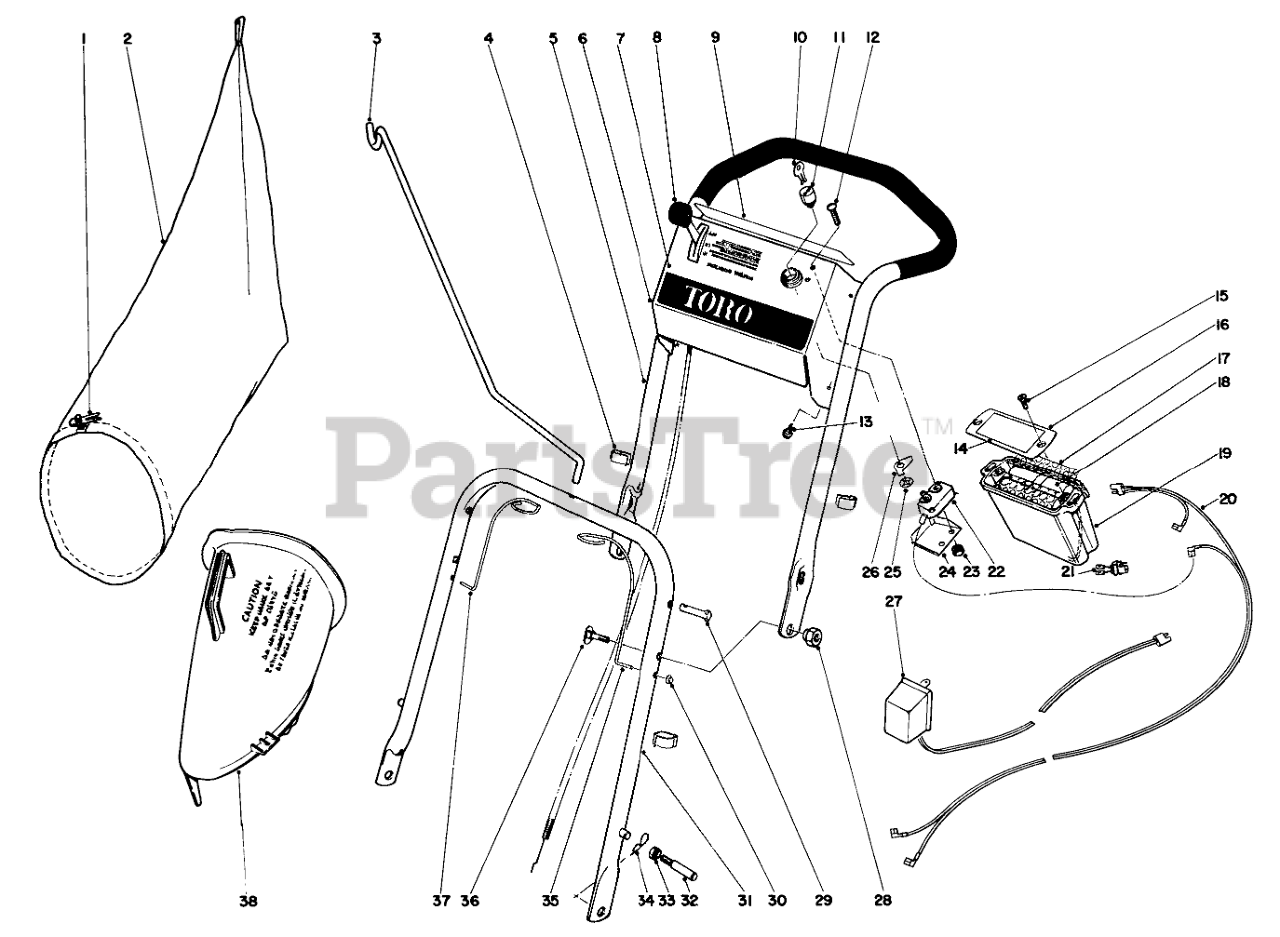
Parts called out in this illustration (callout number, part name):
1	BAG CORD FASTENER
2	Grass Bag (Incl. Ref. No. 1)
3	Bag Hanger Rod
4	BOWDEN CLIP
5	Upper Handle
6	Control Plate
7	Decal, Control Plate
8	Throttle Control
9	Decal, Safety
11	Key Hsg.
13	SCREW-HWHTF
14	Decal
16	Cover
17	Spacer
18	Battery Pack
19	Container Pack
20	Wiring Harness
21	Plug & Wire
22	Switch
23	NUT-KEPS
24	Cover Switch
27	Charger
28	Pivot Nut
29	Latch Pin
31	Lower Handle
32	Handle Pin
33	INSERT-THREADED
34	PIN-COTTER, HAIR
35	Latch Spring L.H.
36	HANDLE SCREW
37	Latch Spring R.H.
38	BAG ATTACHMENT
